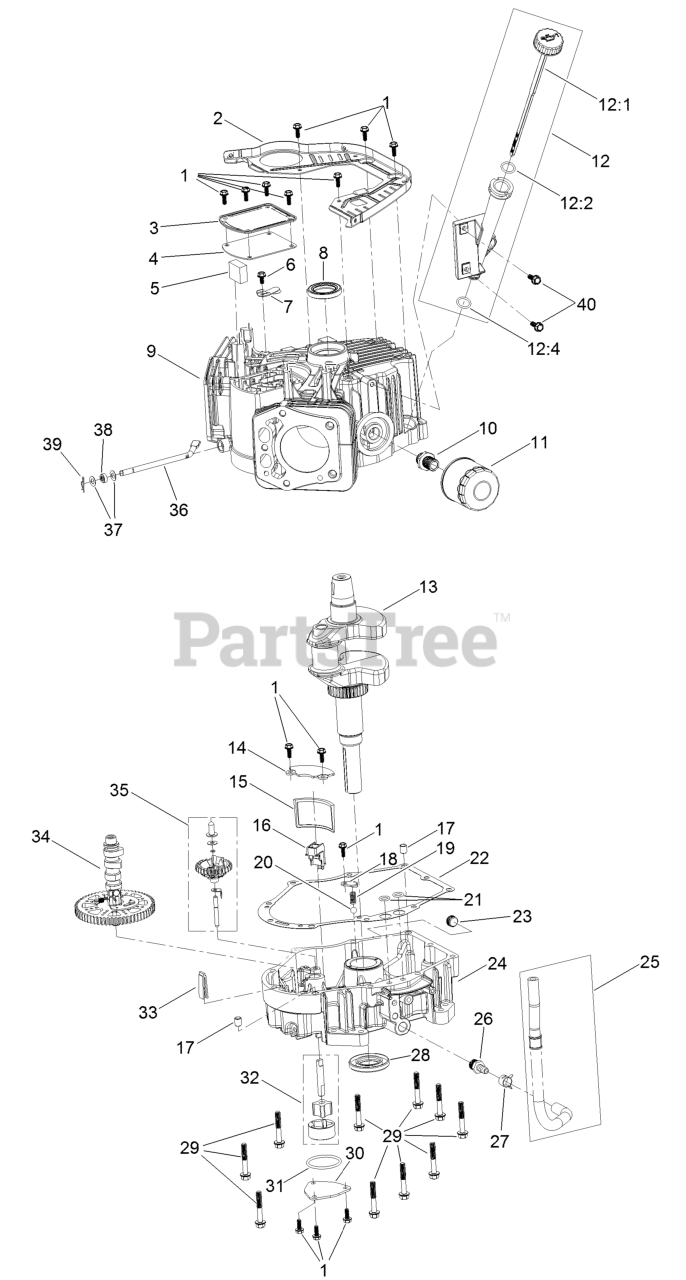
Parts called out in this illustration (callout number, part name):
1	SCREW-HHF
3	COVER-BREATHER
4	GASKET-BREATHER
5	FILTER-BREATHER
6	SCREW-HHF
7	VALVE-BREATHER
8	SEAL-OIL
9	CRANKCASE
12	OIL TUBE ASM
12:1	DIPSTICK
13	CRANKSHAFT
14	COVER-SCREEN, OIL
15	SCREEN-OIL
16	RETAINER-SCREEN
17	PIN-DOWEL
18	PLATE-RETAINER
20	VALVE-BALL
22	GASKET-COVER, CRANKCASE
23	PLUG-DRAIN
24	COVER-CRANKCASE
25	OIL DRAIN HOSE ASM
26	FITTING-HOSE
27	CLAMP-HOSE
29	SCREW-HHF
30	COVER-OIL PUMP
32	OIL PUMP ASM
33	DEFLECTOR-OIL, RUBBER
34	CAMSHAFT
36	SHAFT-GOVERNOR
37	WASHER-PLAIN
38	SEAL-OIL
39	PIN-HAIR
40	SCREW-HHF
